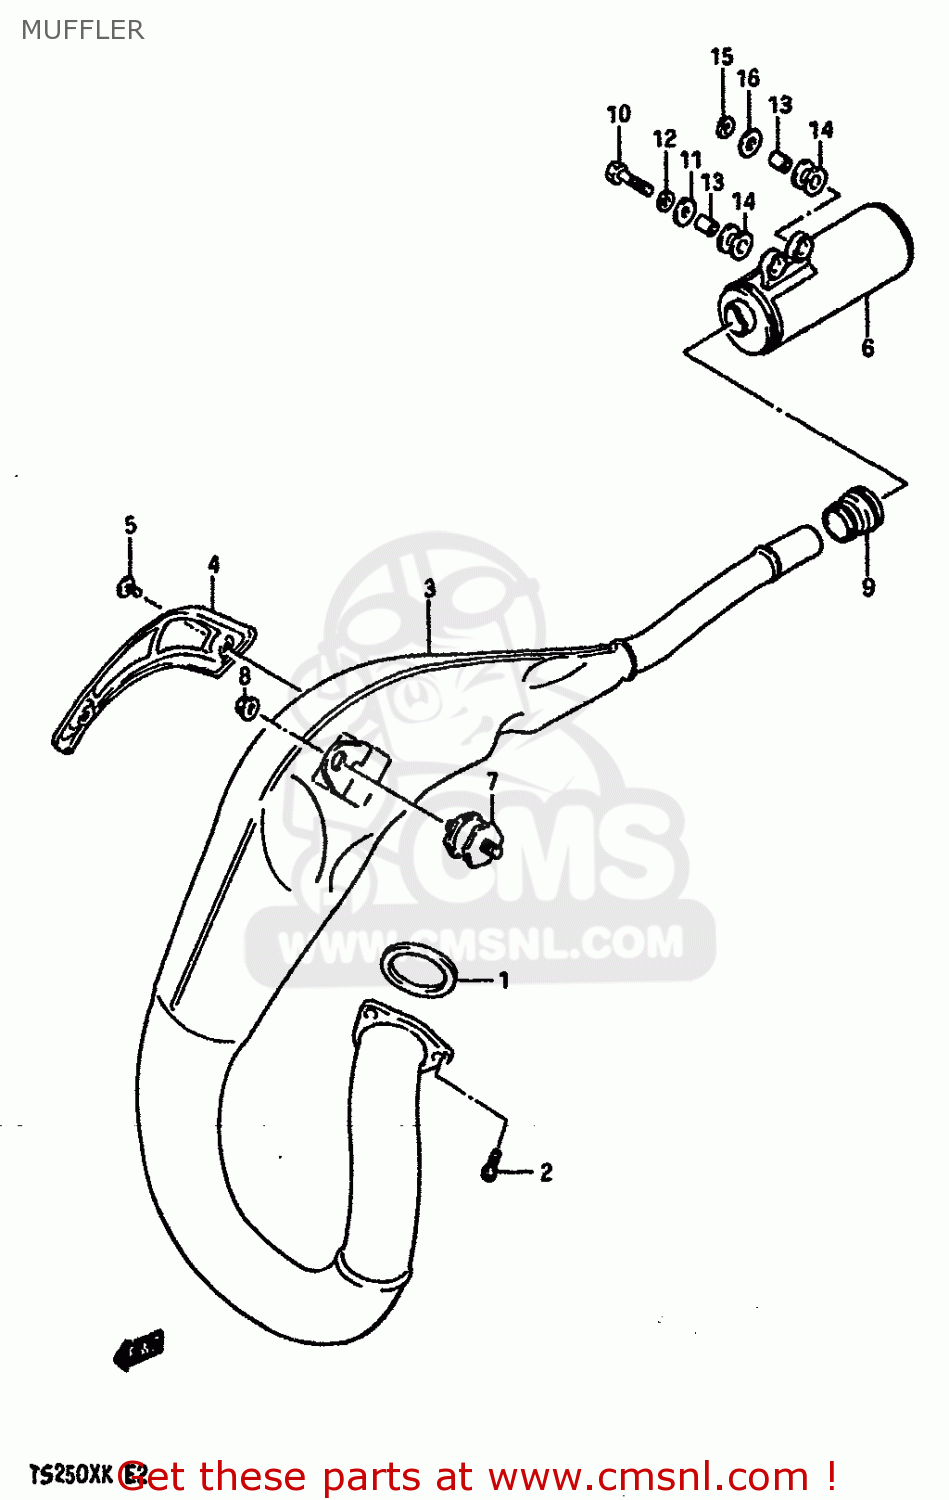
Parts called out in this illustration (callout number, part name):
1	GASKET,EXHAUST PIPE
2	PLUG ,6X20
3	BODY,MUFFLER,1ST
4	COVER,MUFFLER
5	SCREW
6	BODY,MUFFLER,2ND
7	DAMPER,MUFFLER SUPPORT
8	NUT 8MM
9	Muffler Connector
10	BOLT
11	WASHER (8.5X20X1.6)
12	WASHER,LOCK,8.
13	SPACER (8.6X12X17.5)
14	CUSHION
15	WASHER,LOCK,8.
16	WASHER (8.5X20X1.6)
